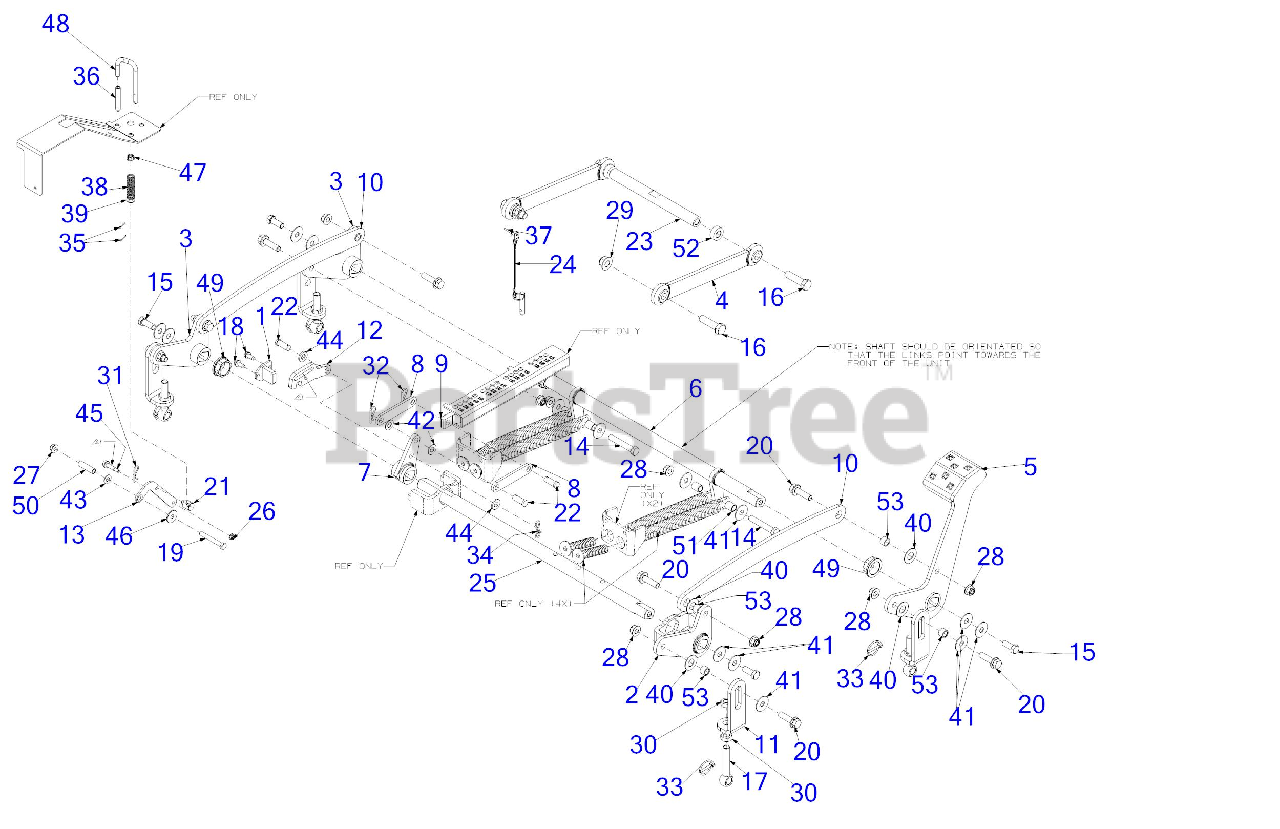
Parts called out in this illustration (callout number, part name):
6	FRONT DECK LIFT SHAFT
7	DECK LIFT HUB ASSEMBLY (LH)
8	DECK LIFT LINK
9	DECK LIFT LINK
13	PIVOT LOCKOUT LINK
14	SCREW-HEX 1/2-13 X 3.00
15	SCREW 1/2-13 x 1.25 GR5
16	SCREW 5/8-11 x 2.25 GR5
17	EYE BOLT 5/8-11 X 3.63
18	SCREW 5/16-18 x .750
19	SCREW 3/8-16 x 2.75 GR5
20	FLANGE BOLT 1/2-13:1.75:GR5
21	BRAKE FERRULE
22	CLEVIS PIN .500 x 1.25
23	FRONT LIFT SHAFT
24	DETENT PIN
25	LIFT SHAFT 1.25 DIA
26	FLANGE LOCK NUT
29	FLANGE LOCK NUT
30	HEX NUT
31	INTERNAL COTTER PIN
32	COTTER PIN
34	PIN:COTTER
35	COTTER PIN 3/32
37	FULL TUBULAR RIVET
38	COMPRESSION SPRING .656 ODX 2.445"
39	FLAT WASHER
40	FLAT WASHER .760ID X1.49OD x .06
41	WASHER .51 x 1.5 x .07
42	FLAT WASHER .510 x 1.00 x .060
43	FLAT WASHER
44	FLAT WASHER .510 x 1.000 x .125
45	SHOULDER SCREW
46	SHOULDER SPACER
47	BUSHING .380 ID
48	DECK LOCK OUT ROD
49	FLANGE BEARING
51	SPACER 0.535 X 0.68 X 0.83
